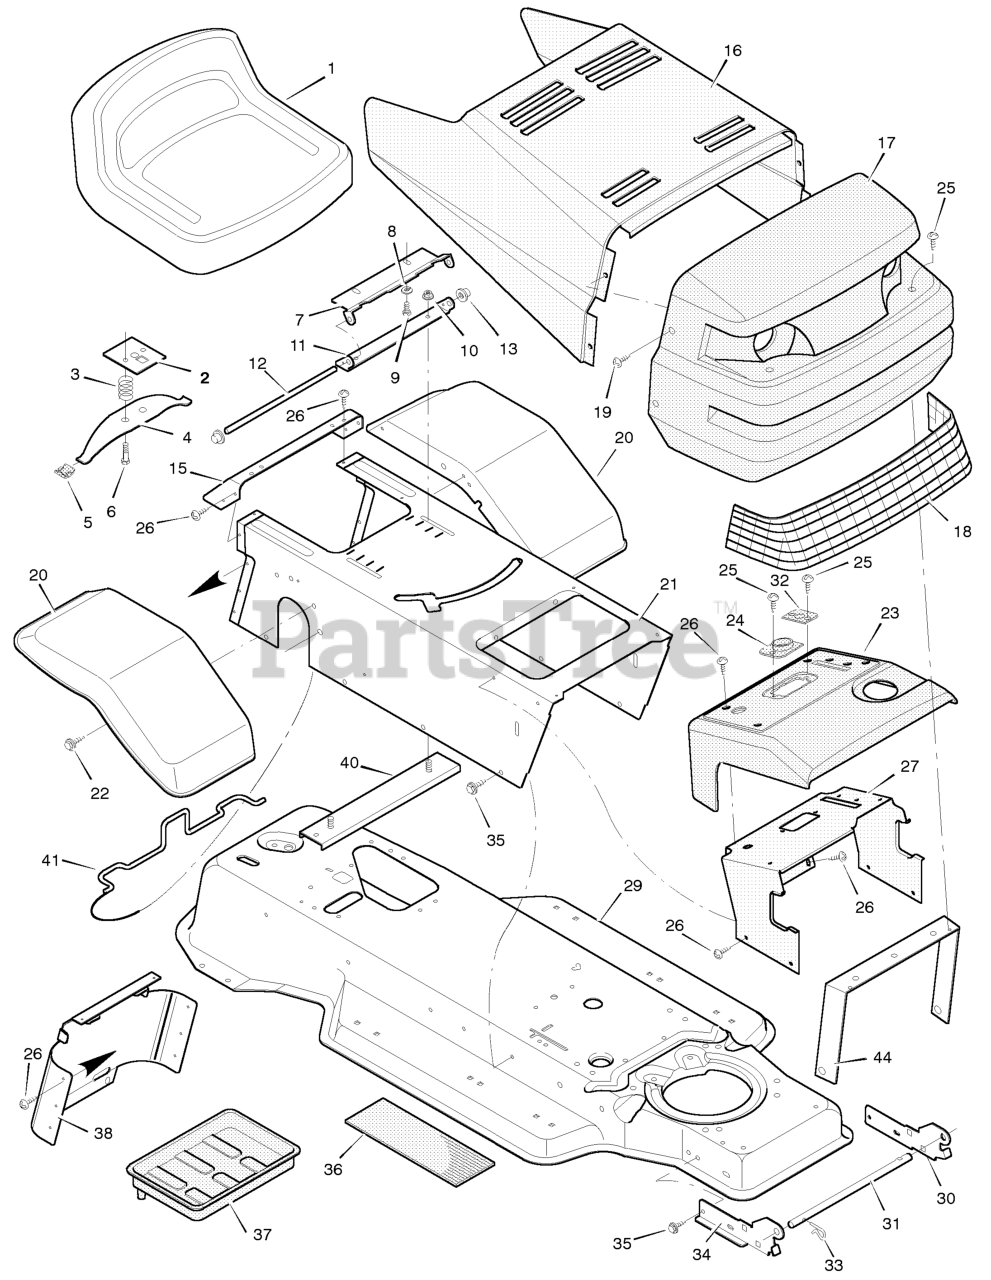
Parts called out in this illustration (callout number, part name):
2	Plate Assembly, Switch
3	Spring, Compression
4	Spring, Seat
5	Glide, Spring
6	Bolt, Shoulder
7	Support, Seat
8	Lockwasher
9	Bolt, Hex
10	Locknut, Flange
11	Bracket, Pivot
12	Rod, Pivot
13	Cap, Push On
15	Fender, Apron
17	Grille Assembly
21	Console Assembly
23	Dash Panel
24	Bearing, Steering
26	Screw
27	Support, Dash
29	Frame Assembly
30	Bracket, Left Grille
31	Rod, Pivot
32	Bearing
33	Pin, Hair
34	Bracket, Right Grille
37	Tray, Battery
38	Cap, Console
39	Bolt
40	Channel Assembly
41	Clamp, Battery
44	Brace, Grille
